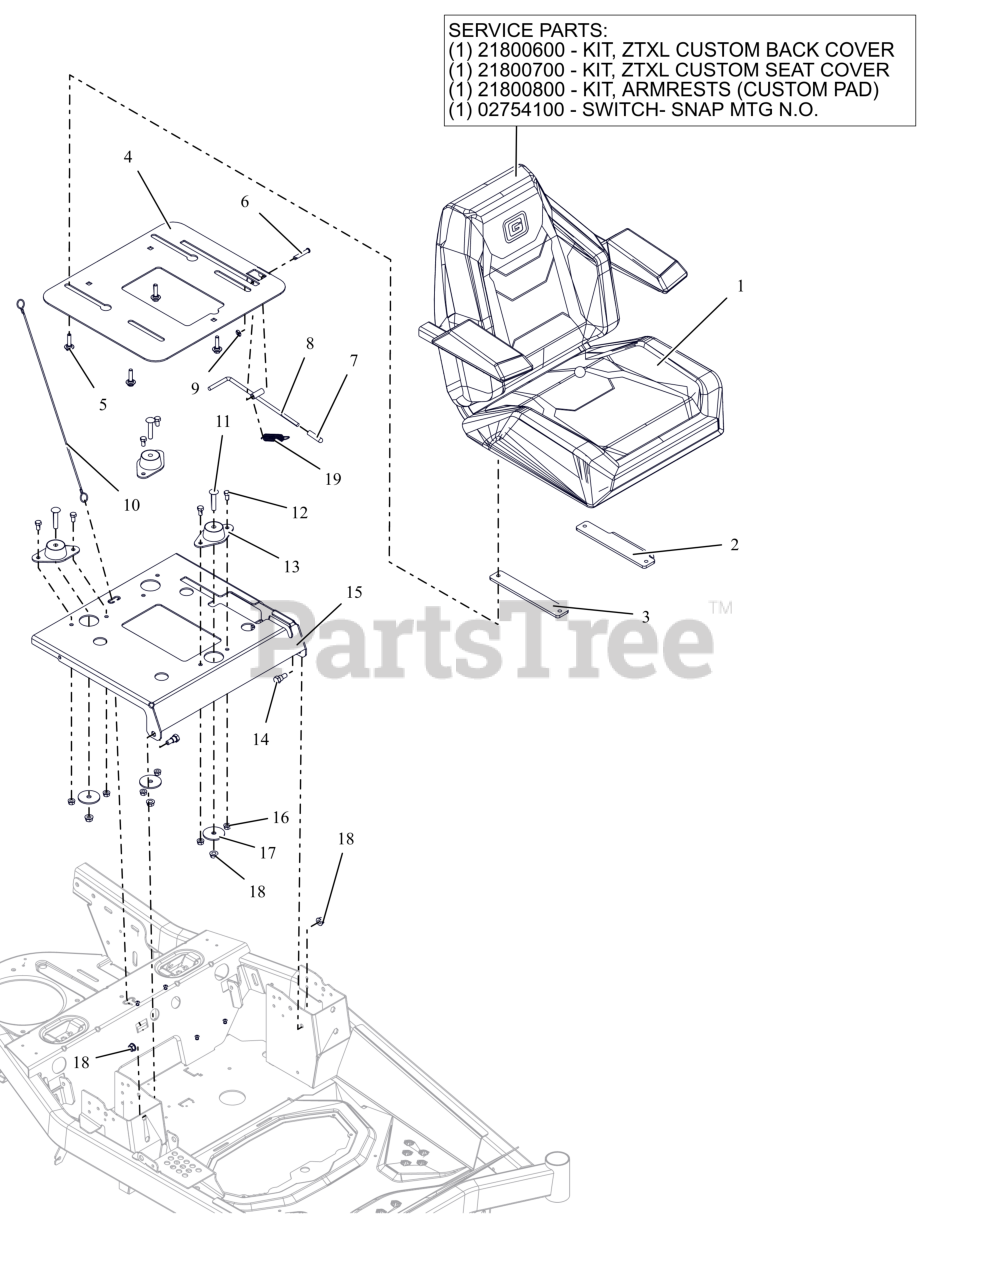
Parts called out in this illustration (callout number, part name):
1	SEAT- ZTXL MY23 (WOOD)
1	KIT- ZTXL CUSTOM BACK COVER
1	KIT- ZTXL CUSTOM SEAT COVER
1	KIT- ARMRESTS (CUSTOM PAD)
1	SWITCH- SNAP MTG N.O.
2	ADJUSTER-PLATE-SEAT
3	SPCR- SEAT PLATE
4	PLATE-SEAT-ISOLATOR
5	BLT, SHLDR .31-18 X .175
6	PIN, CLEV .309X1.75 ZCC
7	GRIP- BLACK .31X1.50
8	WLDMT- LATCH- SEAT
9	NUT-PUSH .312
10	LANYARD, SEAT CABLE .093X19.5
11	BLT,RHSSN.375-16X2.00 G5 ZCC
12	BLT, HEX .31-18X.625 G5 ZCC
13	MOUNT- FAIL-SAFE COMPRESSION
14	BLT-SHLDR .50X.38 ZCC
15	BRKT-SEAT-ISOLATOR MTG
16	NUT,LK-CTR-FLG .31-18 GF ZCC
17	WSHR-FL-STL 0.406X2X0.125 ZCC
18	NUT-LK-CTR-FLG .375-16 GF ZCC
19	SPRG, EXT .653 X .063 X 2.755
